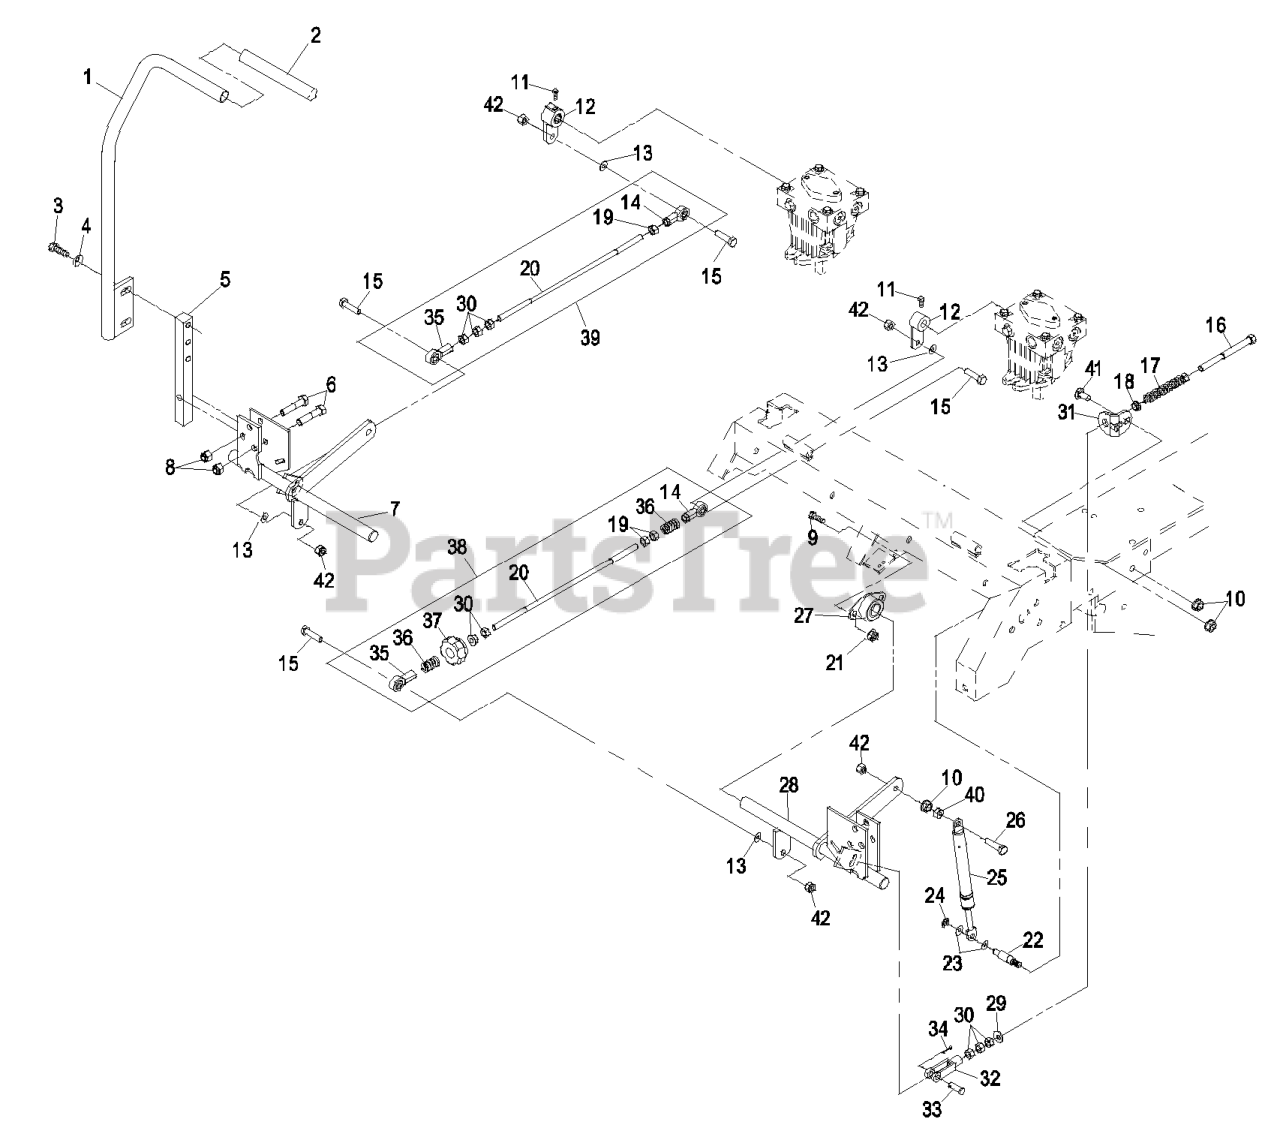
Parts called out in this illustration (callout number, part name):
1	RH LEVER ASM
2	GRIP-CONTROL, MOTION
3	SCREW-HH
4	WASHER-BELLEVILLE
5	ARM-SHAFT, CONTROL
6	SCREW-HH
8	NUT-LOCK, NI
9	SCREW-HH
11	SCREW-SET
12	ARM-CONTROL
13	WASHER-FLAT
14	BALLJOINT-LH
15	SCREW-HH
16	BOLT-RETURN, NEUTRAL
17	SPRING-RETURN, NEUTRAL
18	BUSHING-NYLON, FLANGED
19	NUT
20	LINK-ROD, TRACKING
21	NUT-HHF, WHIZ
22	PIN-DAMPER
23	WASHER-PLAIN
24	RING-RETAINING, EXT
25	DAMPER-CONTROL, MOTION
26	SCREW-HH
27	BEARING-FLANGE, SIDE
28	CONTROL-MOTION, LH
29	WASHER-FLAT
30	NUT-HEX
31	TAB-ADJUSTMENT
32	YOKE-ADJUSTABLE
33	PIN-CLEVIS
34	PIN-COTTER
35	BALLJOINT-RH
36	SPRING-COMPRESSION
37	KNOB-TRACKING
38	TRACKING ROD ASM
39	TRACKING ASM
40	NUT-HEX
41	SCREW-CARR
42	NUT-LOCK, NI
